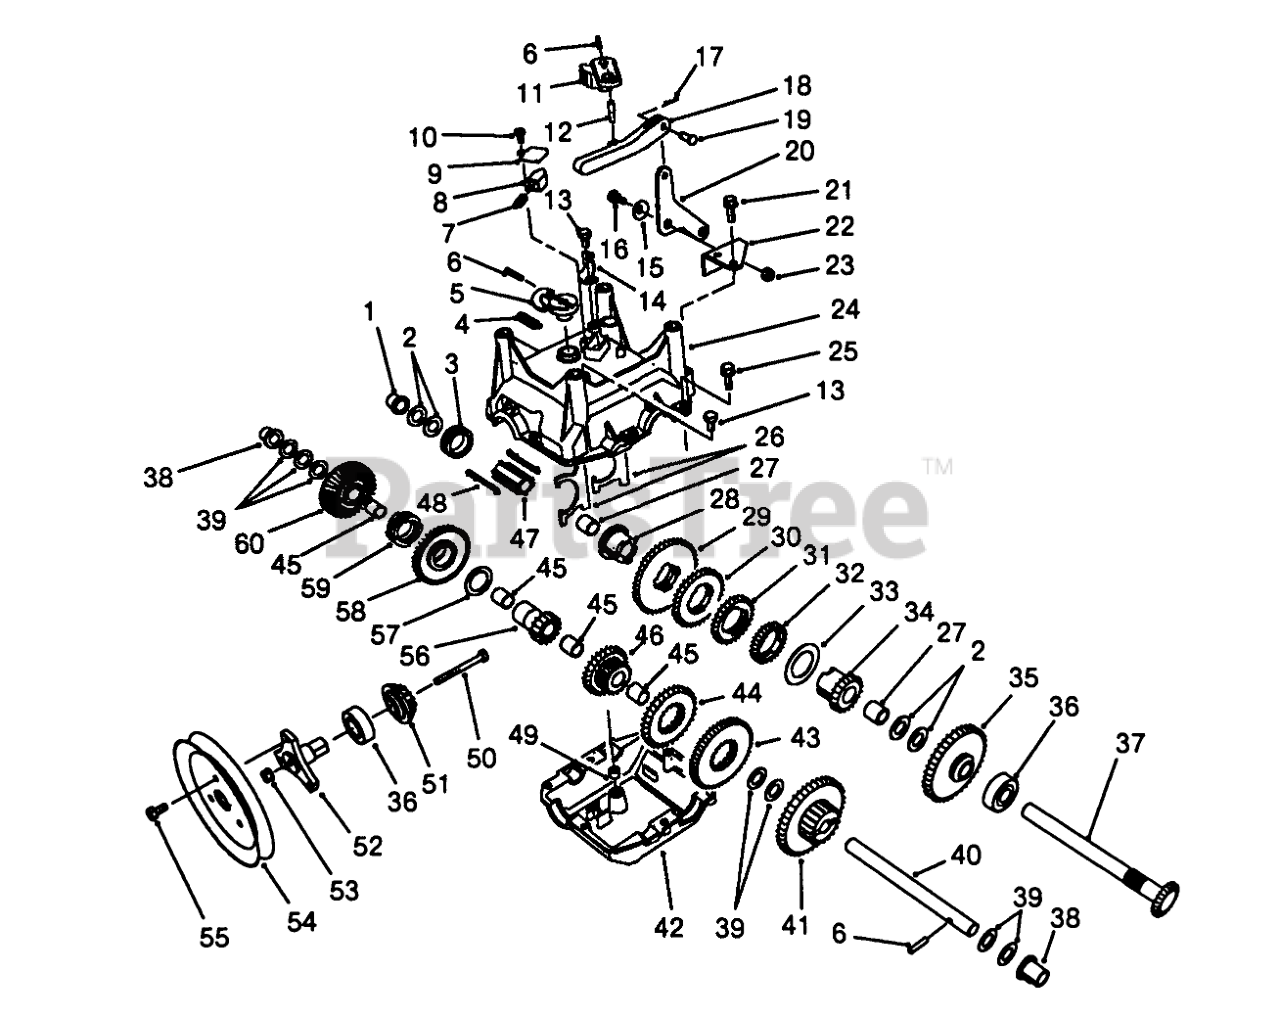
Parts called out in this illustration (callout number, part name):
1	BUSHING-FLANGE, OUTPUT
2	BEARING-THRUST
3	COLLAR-SHIFT
4	SPRING-EXTENSION
5	LEVER
6	PIN-SPRING
7	SPRING-DETENT
8	BUTTON-DETENT
9	COVER-DETENT
10	SCREW-HWH
11	LEVER-SHIFT, GEAR
12	PIN-LINK, GEAR SHIFT
13	SCREW-HWH
14	BRACKET-CABLE
15	WASHER-CURVED
16	SCREW-SHOULDER
17	PIN-COTTER
18	LINK-SHIFT, GEAR
19	PIN-CLEVIS
20	BELLCRANK
21	SCREW-HWH
22	BRACKET-BELLCRANK
23	NUT-LOCK, NI
24	GEARCASE-UPPER, CASING
26	YOKE-SHIFT
27	BUSHING-OUTPUT
28	SLEEVE-GEAR
29	GEAR-45 T
30	GEAR-34 T
31	GEAR-27 T
32	GEAR-29 T
33	WASHER-THRUST
34	GEAR-SLEEVE, 19 T
35	GEAR-41 T
36	BEARING-BALL
37	SHAFT-OUTPUT
38	BUSHING-INTERMEDIATE
39	WASHER-THRUST
40	SHAFT-INTERMEDIATE
41	GEAR-19/41 T
42	GEARCASE-LOWER, CASING
43	GEAR-51 T
44	GEAR-33 T
45	Bushing-Output
46	Gear-26T
47	Sleeve-Shift
48	KEY-SHIFT
49	BUSHING-YOKE
50	SCREW-HH
51	PINION-BEVEL
52	HUB-PULLEY
53	NUT-HHF
54	TRACTION-SHEAVE, HALF
55	SCREW
56	GEAR-BEVEL, 15 T
57	WASHER-THRUST
58	Gear-Bevel 36T
59	Collar-Shift
60	Gear-Bevel Reverse 36T
